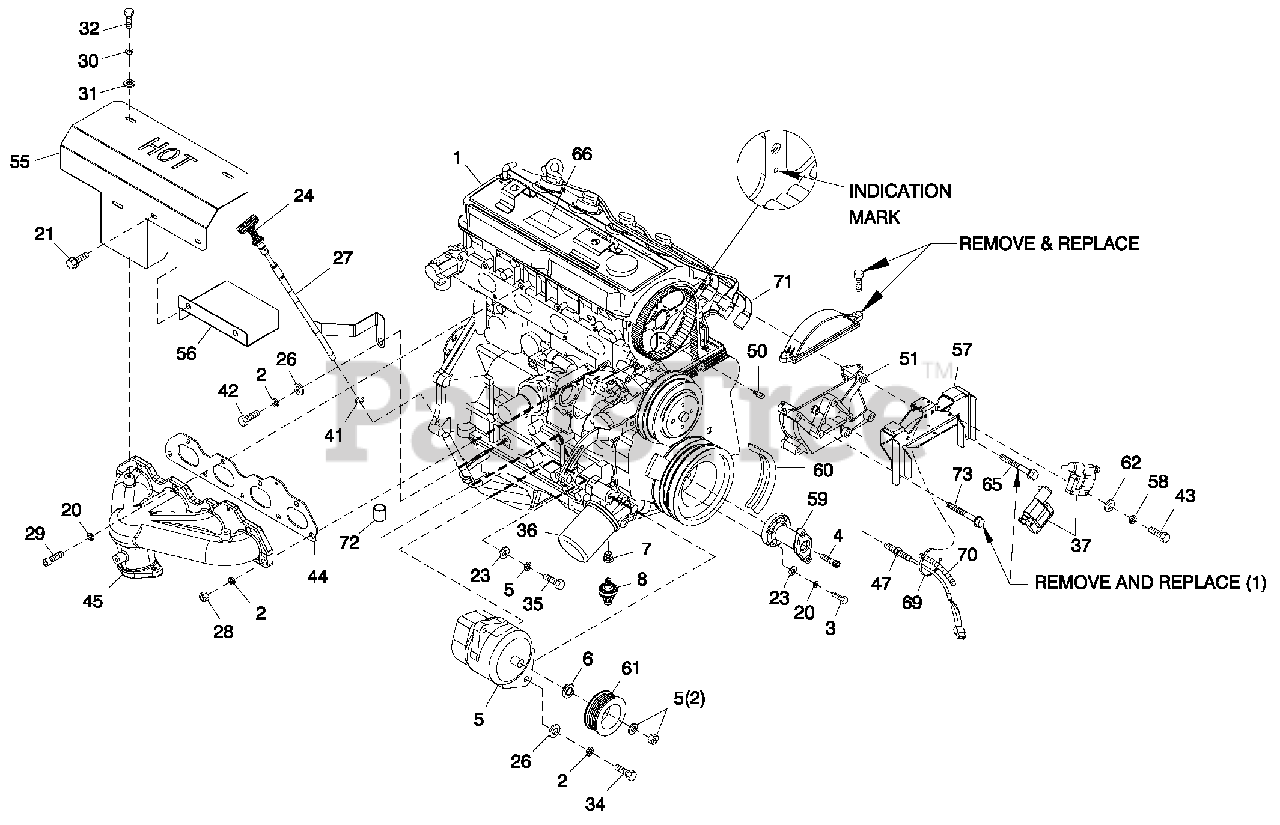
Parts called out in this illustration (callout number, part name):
1	ENGINE 2.4LG2 CERTIFIED
2	WASHER LOCK M10
3	SCREW HHC M8-1.25X35G8.8
4	SCREW SHC M14-1.5X 35 G10.9
5	ALTERNATOR DC W/O U T P ULLEY
6	SPACER DC ALTERNATOR P U LLEY
7	ADAPTOR 1/8 NPTF TO 1/8 BSPT
8	SWITCH OIL PRESS URE 10 PSI 2 POL (R-PANEL)
20	WASHER LOCK M8-5/16
21	SCREW THF M6-1 X 16 N WA Z/JS
23	WASHER FLAT 5/16-M8 ZINC
24	ASSY DIPSTICK W/TEXT GTH-530
26	WASHER FLAT 3/8-M10 ZINC
27	ASSY DIPSTICK T U BE 2.4 G2
28	NUT HEX M10-1.25 G8 YEL CHR
29	SCREW SHC M8-1.25 X 25 G12.9
30	WASHER LOCK M6-1/4
31	WASHER FLAT 1/4-M6 ZINC
32	SCREW HHC M6-1.0X12G8.8
34	SCREW HHC M10-1.5X 60 G8.8
35	SCREW HHC M8-1.25X 25 G10.9
36	FILTER 1.5L/2.4LG2 OIL
37	COIL-2.4LG2 IGNITION
40	SCREW HHC M6-1.0X 25 G8.8
41	O-RING SIZE 9.0MM X 2.0MM NITR
42	SCREW HHC M10-1.25 X 20 C8.8
43	SCREW HHM #10-32X1-1/4
44	GASKET EXHAUST MANIFOLD
45	EXHAUST MANIFOLD G2 (MACHINE) (25KW, 35KW & 45KW)
47	ASSY MAGPICK U P(3/8-24 MALE)
51	COVER CAM GEARG2 REWORKED
53	GASKET INTAKE MANIFOLD
54	SPACER 2.4L G2 FLEX PLATE
55	SHIELD HEAT
56	SHIELD HEATSML
57	BRACKET ASM-2.4L COILG2
58	WASHER LOCK #10
60	POLY V-BELT G2 (3600 RPM)
61	P U LLEY DC ALTERNATOR (3600 RPM)
62	WASHER FLAT #10 ZINC
64	BRACKET, SIGNAL CONDITIONER
65	SCREW HHC M8-1.25X 70 G8.8
66	BRACKET SIGNAL CONDITONER
69	TIE WRAP U L7.4"X .19" BLK
70	COND UIT FLEX .25"ID
71	SPARK PLU G WIRE SET 2.4L G2 IG
72	PLU G TAPER
73	SCREW HHC M8-1.25X 65 C8.8
